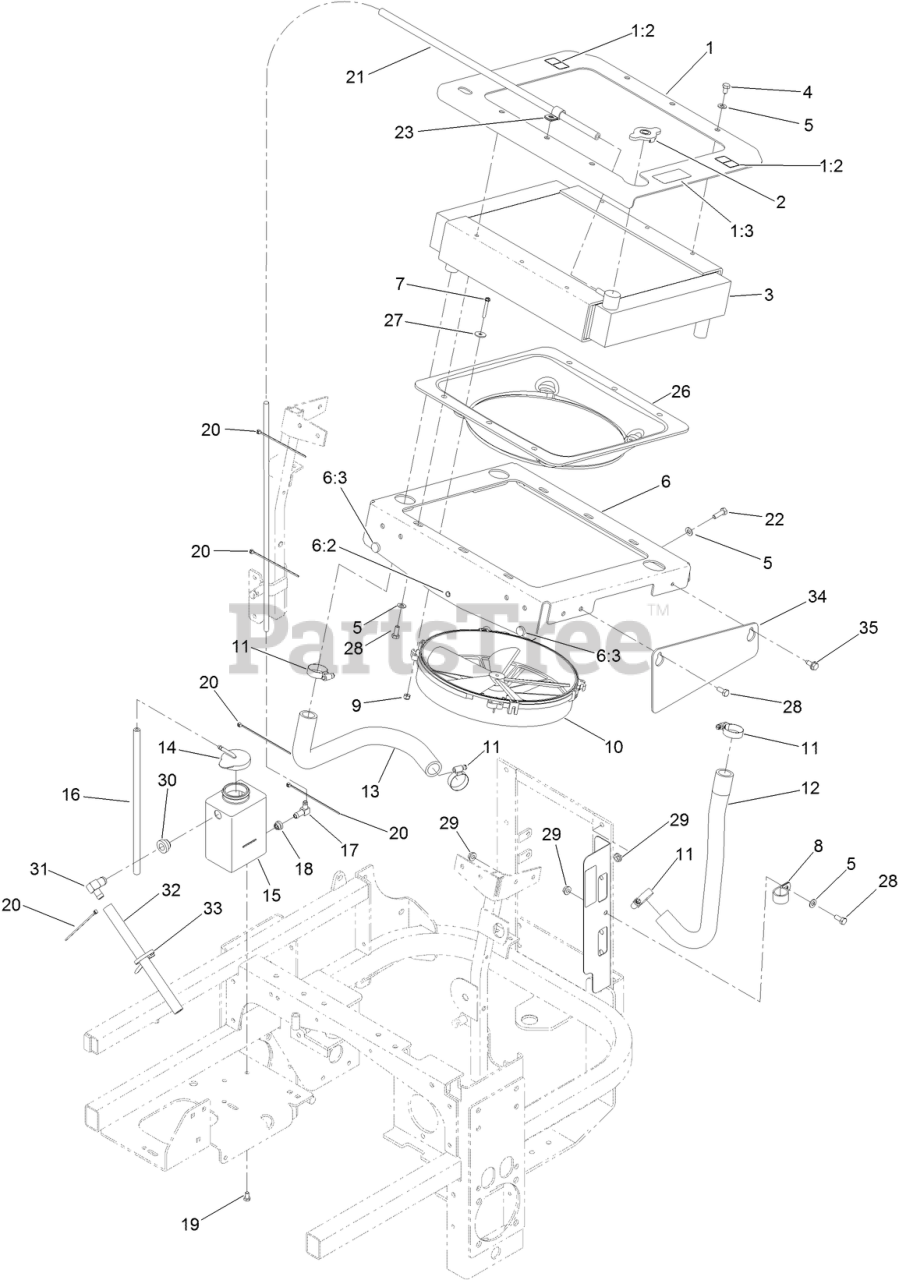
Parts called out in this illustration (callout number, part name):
1	TOP RADIATOR PLATE ASM
1:2	DECAL-SURFACE, HOT
1:3	DECAL-ANTIFREEZE
2	CAP-RADIATOR
3	RADIATOR
4	SCREW-HH
5	WASHER-PLAIN
6	BOTTOM RADIATOR PLATE ASM
6:2	NUT-CLINCH
6:3	BUMPER
7	SCREW-HWH
8	CLIP-LOOM
9	NUT-LOCK, HH
11	CLAMP-HOSE
12	HOSE-RADIATOR, LH
13	HOSE-OUTLET, ENGINE
14	CAP-TANK, OVERFLOW
15	TANK-OVERFLOW
16	HOSE-LINE, FUEL
17	FITTING-ELBOW, 90 DEG
19	SCREW-HH
20	TIE-CABLE
21	HOSE-OVERFLOW
22	SCREW-HH
23	CLIP-LOOM
26	SHROUD-COOLING, ENGINE
27	WASHER
28	SCREW-HH
29	NUT-HF
31	FITTING-ELBOW
32	HOSE-OVERFLOW
33	TIE-PLASTIC
34	SHIELD-RADIATOR
35	SCREW-HWHTF
